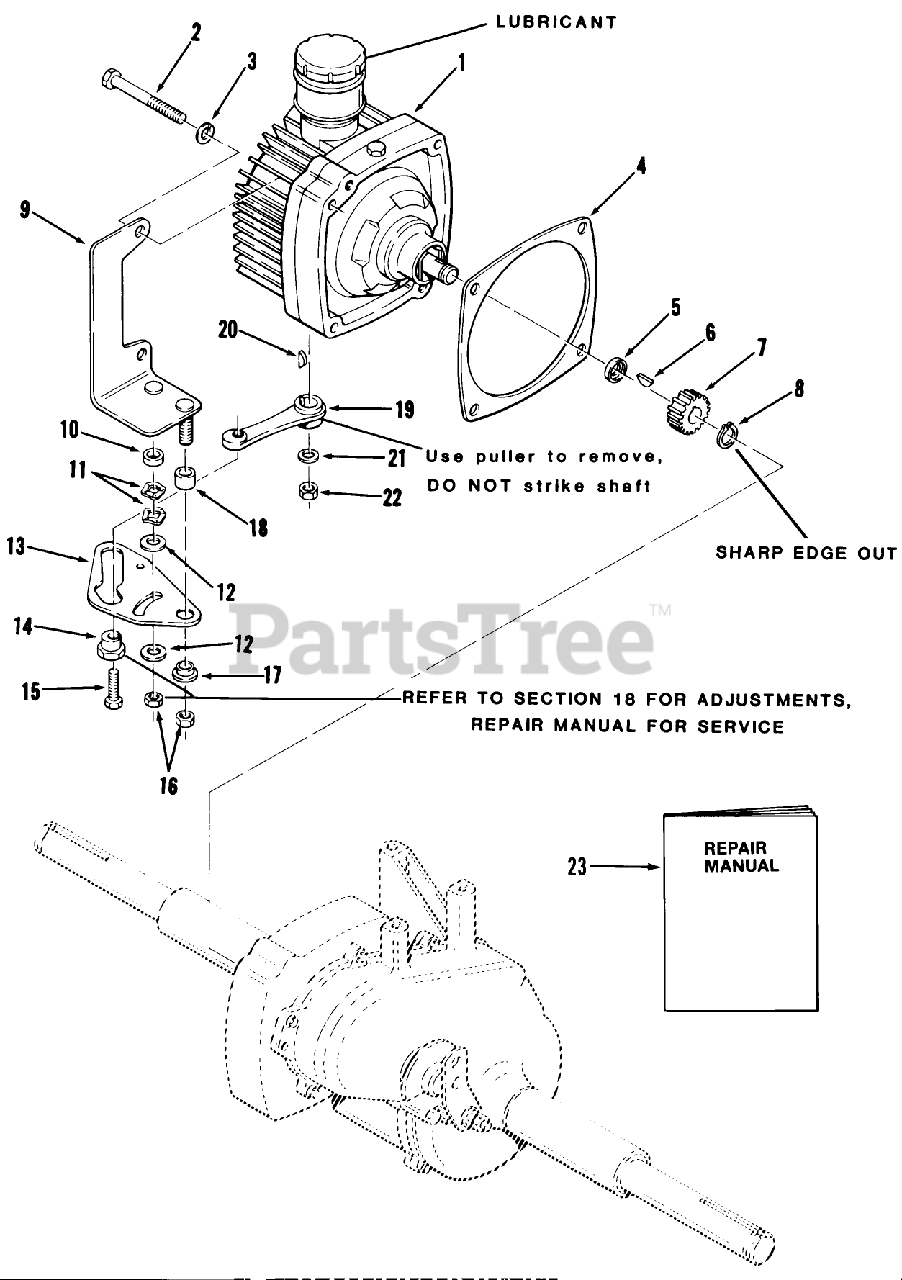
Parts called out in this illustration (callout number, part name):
1	Pump & Motor
2	Screw-Hex. Hd.
3	LOCKWASHER
4	GASKET HYDRO
5	SPACER-GEAR
6	KEY WOODR 1/8X1/2 DI
7	Gear 12 Tooth
8	SNAP RING
9	ASSY CONTROL SUPP R
10	SPACER-FRICTION
11	WASHER-SPRING DISC
12	FRICTION WASHER
13	CAM-SPEED CONTROL (NS)
15	Bolt
17	CAM-SPACER
18	SPACER-PIVOT
19	ARM-SPEED CONTROL
20	KEY WOODR 1/8X1/2 DI
21	Washer
22	Nut
23	Automatic Transmission Repair Manual
